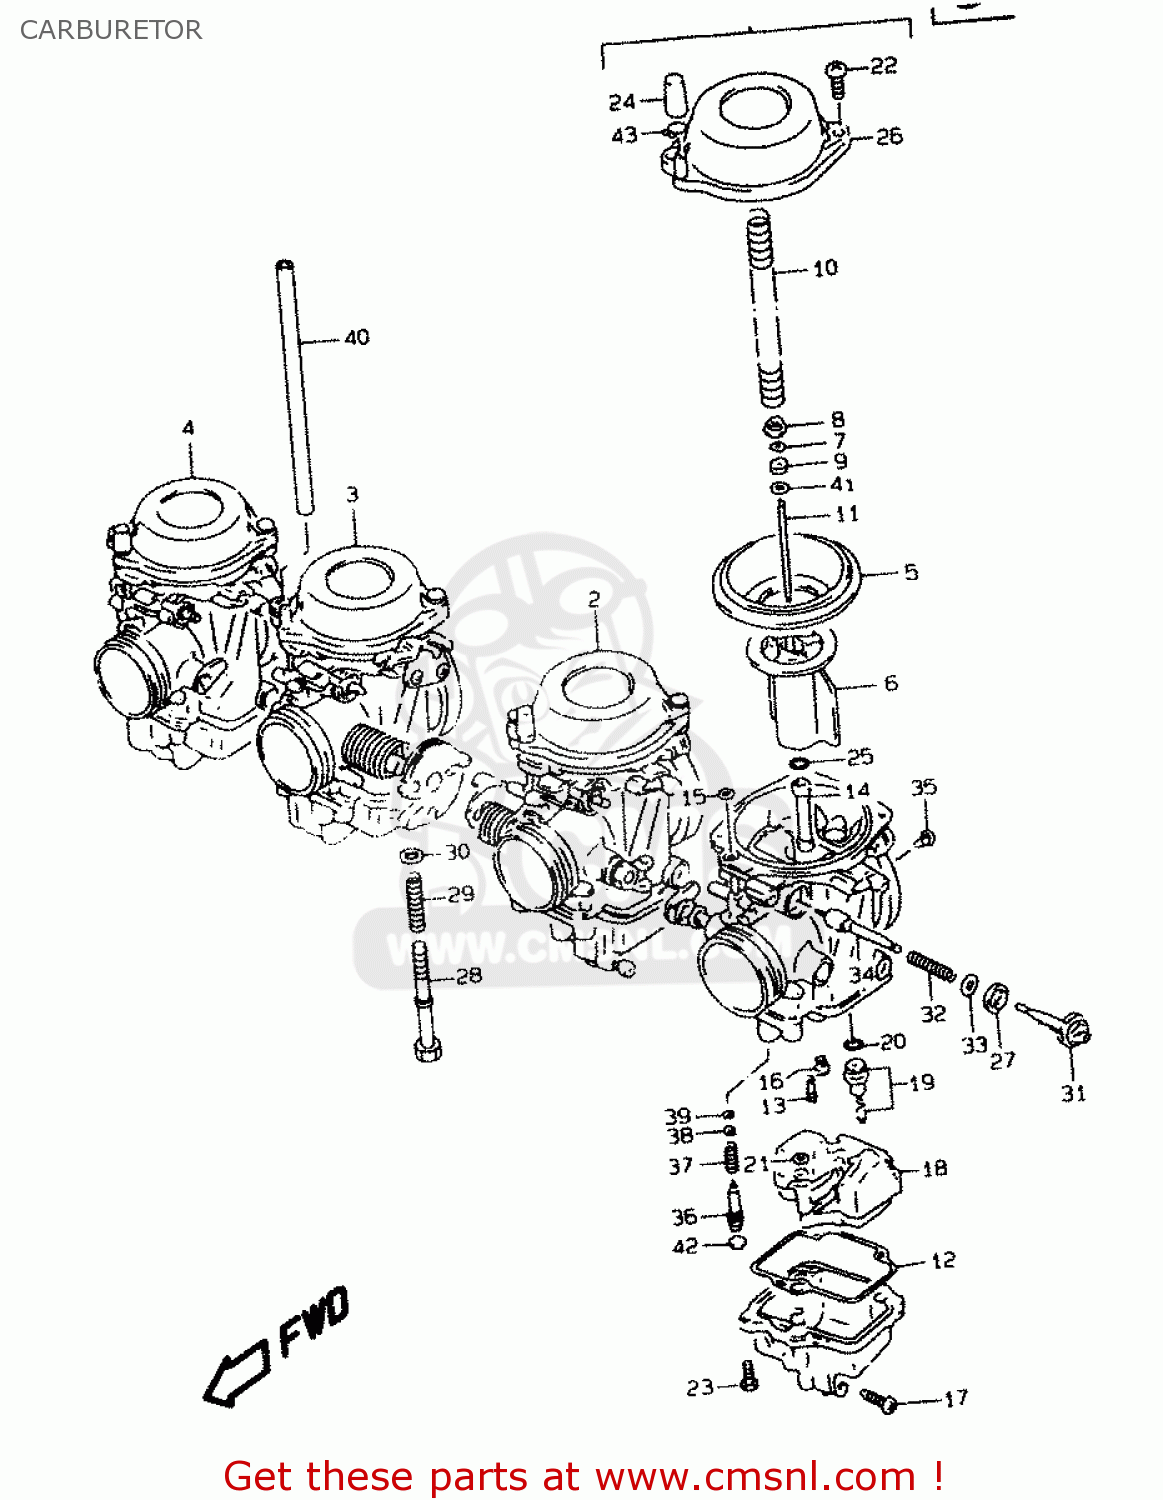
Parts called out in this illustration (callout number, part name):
1	CARBURETOR ASS
2	CARBURETOR ASS
3	CARBURETOR ASS
4	CARBURETOR ASS
5	DIAPHRAGM
6	VALVE,PISTON
7	E RING
8	RING
9	RING
10	SPRING
11	NEEDLE,JET
12	GASKET,FLOAT CHAMBER (NAS)
13	JET,PILOT(37.5)
14	JET,NEEDLE(O-8)
15	O RING
16	JET,MAIN(102.5)
17	SCREW,DRAIN
18	FLOAT ASSY
19	VALVE ASSEMBLY,NEEDLE
20	O RING
21	O-RING,NEEDLE VALVE
22	SCREW
23	SCREW
24	CAP
25	O RING
26	COVER,DIAPHRAGM
27	CAP,STARTER
28	SCREW,ADJUSTER
29	SPRING
30	WASHER
31	HOLDER,GUIDE
32	SPRING
33	WASHER
34	PLUNGER ASSY
35	JET,PILOT AIR,1.4
36	SCREW,PILOT
37	SPRING
38	WASHER
39	O RING,PILOT AIR SCREW
40	HOSE(5X9X600)
41	WASHER
42	PLUG
43	CLIP
